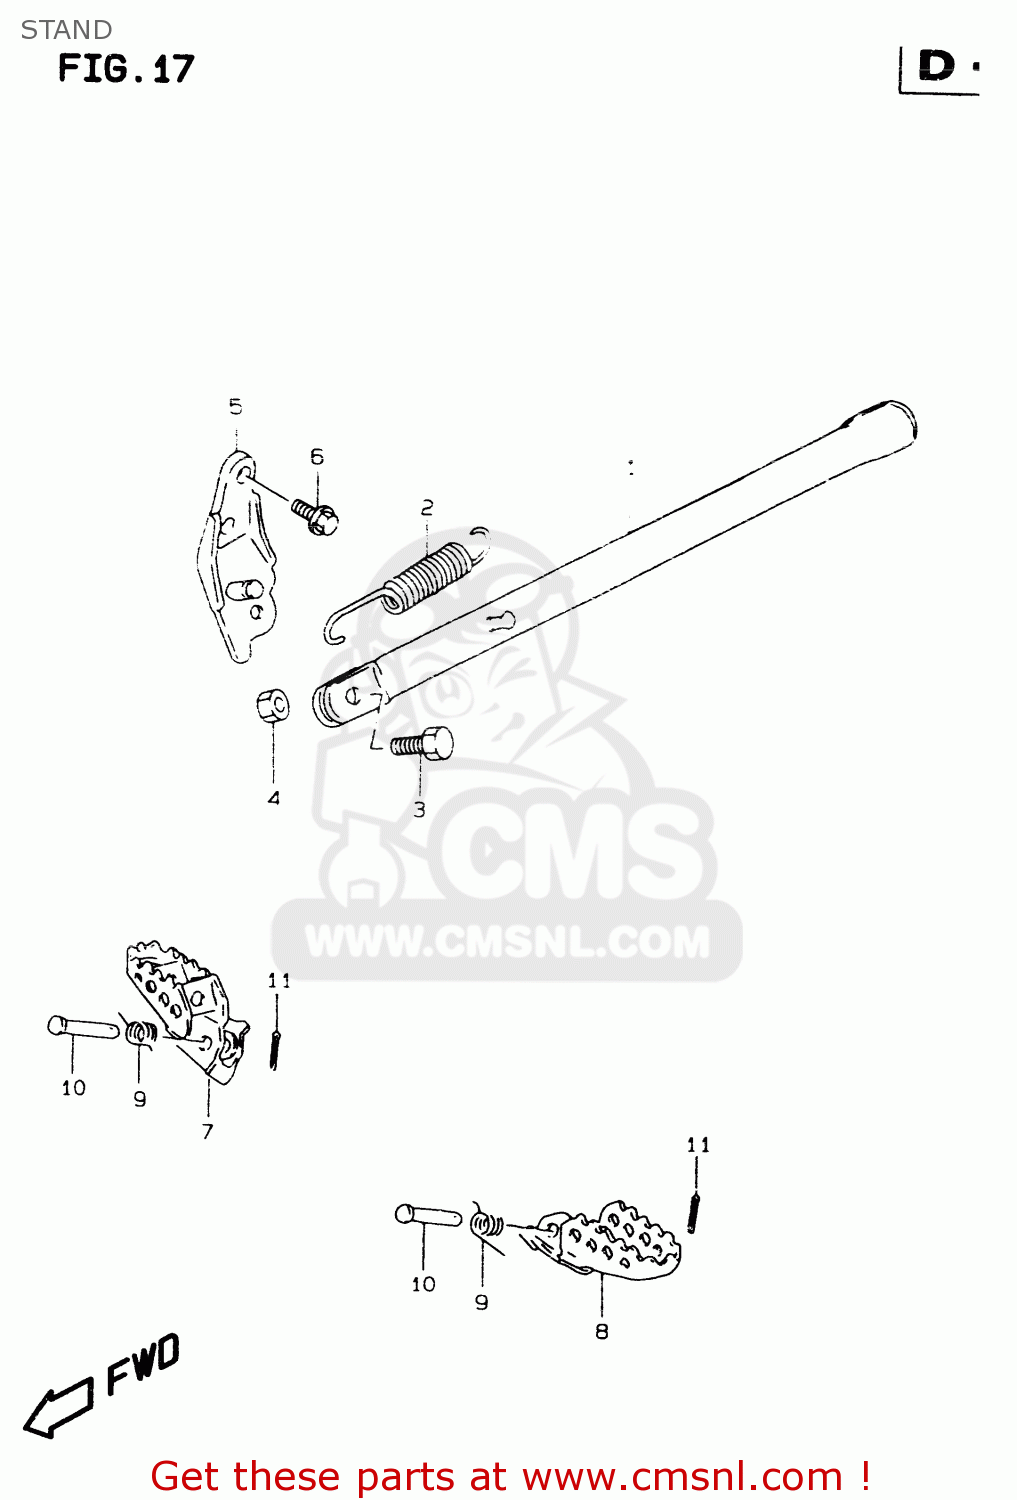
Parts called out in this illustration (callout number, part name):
1	STAND,PROP(BLACK)
2	SPRING
3	BOLT(8X25)
4	NUT
5	BRACKET,PROP STAND(BLACK)
6	BOLT
7	FOOTREST,FR,R
8	FOOTREST,FR,L
9	SPRING
10	PIN
11	PIN
